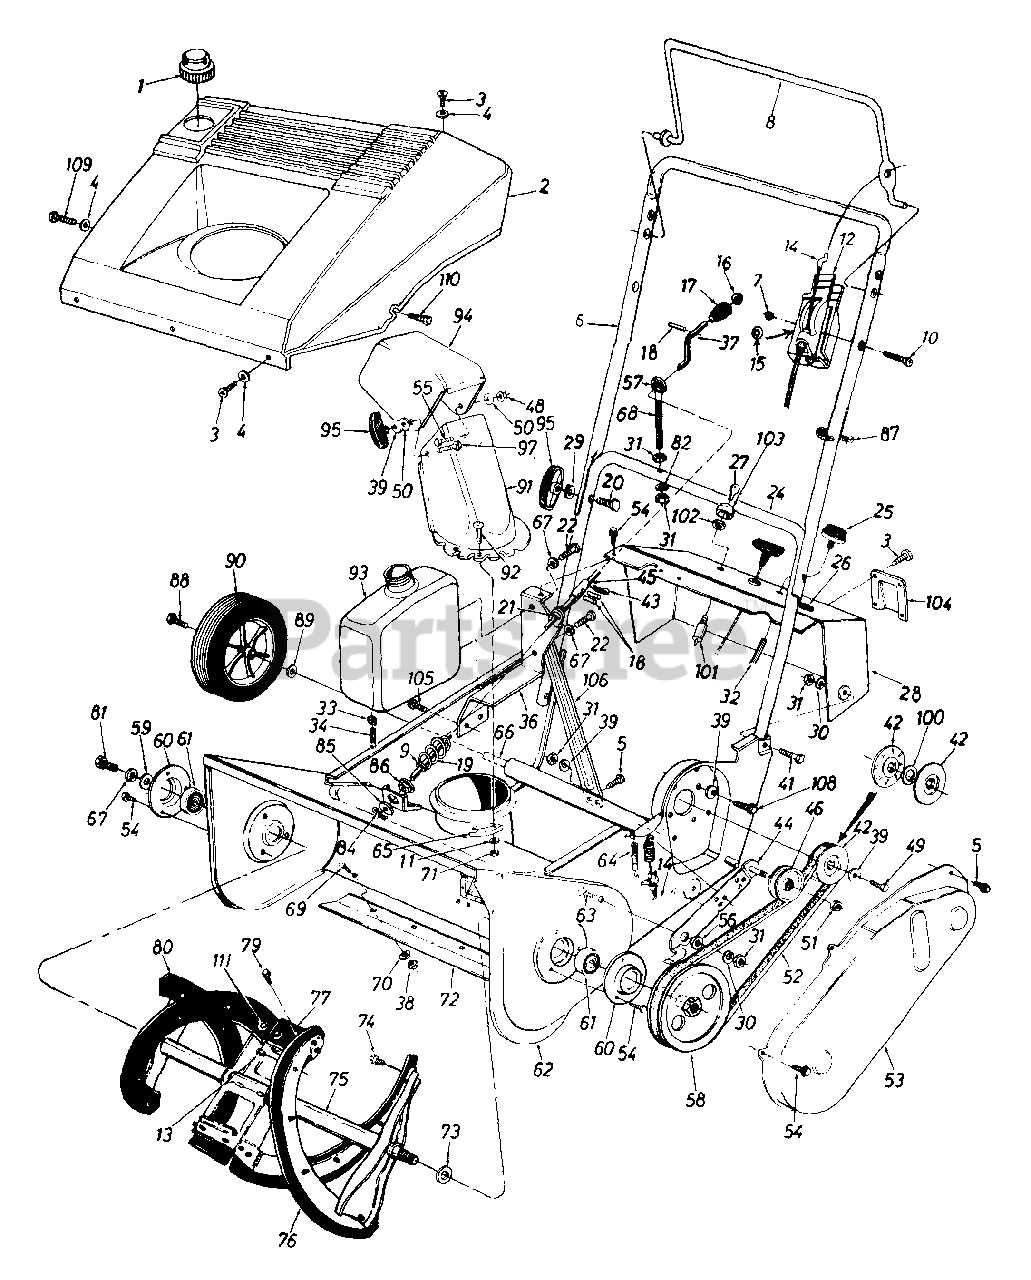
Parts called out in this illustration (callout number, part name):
1	Gas Tank Cap
2	Shroud
3	Hex B-Tap Scr. #10 x .5" Lg.
4	Fl-Wash..203" I.D. x .41"
5	Hex L-Wash. Hd. AB-Tap 1/4 x .62" Lg.
9	Fl-Wash. .385" I.D. x .62"
10	Oval C-Sunk Mach. Scr.
11	Fl-Wash. .281" I.0. x .5" O.D.
12	Throttle Body
13	Pop Rivet .187" Dia.
14	Clutch Cable 35" Lg.
16	Push Cap 3/8" Rod
17	Knob - 3 8" Dia. Hole
18	Roll Pin 1/8" Dia. x .63" Lg.
19	Lower Chute Crank Ass'y.
20	Curved Carriage Bolt 5/16-18 x 1.75" Lg.
21	Chute Crank Grommet
22	Hex Bolt 1/4-20 x .5" Lg.
26	Plastic Plug
30	L-Wash. 5/16" I.D."
31	Hex Nut 5/16-18 Thd.
32	Primer Hose - 9" Lg.
33	Hose Clamp - 1/2" O.D.
34	Gas Line 26" Lg.
36	Gas Tank Support Brkt.
38	Hex Jam Nut 1/4-20 Thd.
39	Bell-Wash. 5/16" I.D. x .937" O.D.
41	Hex Bolt 5/16-18 x 1.5" Lg.
42	3/8" "V"-Pulley Half .625" I.D. x 6.0" 0.D.
43	Cotter Pin 3/32" Dia.
46	Fl-Idler w/Flanges 2.12" O.D.
48	Hex L-Nut 5/16-18 Thd.
49	Hex Bolt 5/16-24 x .75" Lg.
50	Fl-Wash. .344" I.D. x 1.25"
51	Hex Patch L-Nut 3/8-24 Thd.
52	"V"-Belt
54	Hex B-Tap Scr. 1/4" x .38" Lg.
55	Carriage Bolt 5/16-18 x .75"
56	Shld. Spacer .50" Dia. x .27"
57	Plastic Bushing .38" I.D.
58	1/2" "V"-Pulley 1/2-20 L.H. x 6"
59	Fl-Wash 1/4" I.D x 93" O.D.
64	Extension Spring 1.12" Lg.
65	Chute Flange Keeper
66	Wheel Axle 20.6" Lg.
67	L-Wash 1/4" I D."
68	Eyebolt
69	Carriage Bolt 1/4-20 x .50"
70	Fl-Wash. .281" I.D. x .73"
71	Hex L-Nut 1/4-20 Thd.
72	Shave Plate
73	Fl-Wash. .510" I.D x 1.0" O.D.
74	Hex Wash. B-Tap Scr. 1/4 x .62"
76	Rubber Spiral - L.H.
77	Rubber Paddle
79	Hex Wash. B-Tap Scr #10 x .62" Lg.
80	Rubber Spiral - R.H.
81	Hex Wash. TT-Tap Cl-Scr. 1/4-20 x .75" Lg.
82	Saddle Wash. .32" I.D.
84	Cotter Pin 3/32" Dia. x .75"
85	Fl-Wash. .406" I.D. x 1.25"
86	Hex Bushing .385" I D.
87	Cable Tie
88	Hex Tap Scr. 3/8-24 x .5" Lg.
89	Fl-Wash. .510" I.D. x .75"
90	7" Wheel & Tire Ass'y.
91	Lower Chute
92	Truss Mach Scr. 1/4-20 x .75"
93	Fuel Tank - Two Qt.
94	Upper Chute
95	Knob Handle Ass'y.
97	Carriage Bolt 5/16-18 x 1"
100	Fl-Wash. .635" I.D. x .93" O.D
101	Key Switch
102	Ignition Switch Nut 5/8-32 Thd.
103	Ignition Switch Cap
104	Choke Cover
105	Hex Wash. Hd. Tap Scr. 1/4-.5" Lg.
109	Pan Hd. Tap Scr. #10 x 1.25" Lg.
110	Hex Wash. Hd. Tap Scr. 1/4-20 x 1" Lg.
111	Torx AB-Tap Scr. 1/4 x .62" Lg
